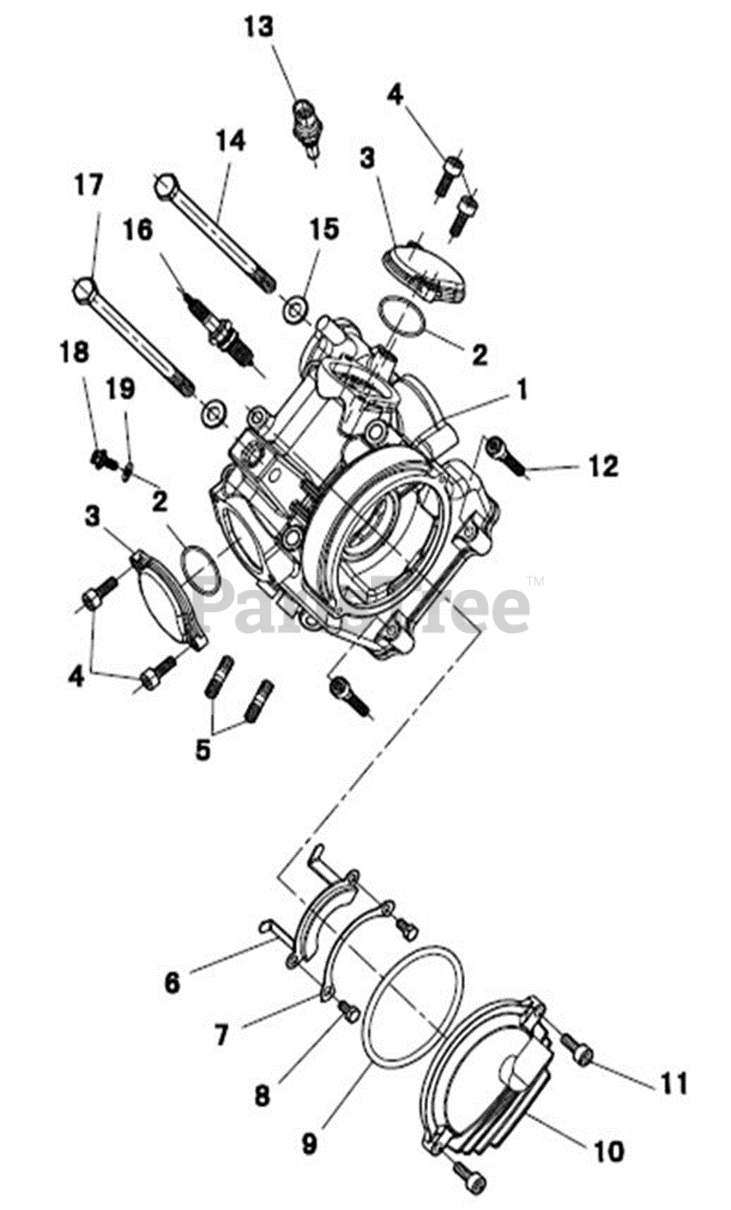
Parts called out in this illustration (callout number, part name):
1	CYLINDER HEAD ASSEMBLY
2	O-RING 58 x 2.4
3	VALVE COVER
4	HEX HEAD CAP SCREWM6X20
5	STUD M8X45
6	CAM BEARING HOLDER
7	BOLTS - SPACING PLATE
8	BOLTS HEXAGON HEAD M6 x 16
9	O-RING 107 x 2.4
10	CAMSHAFT COVER
11	BOLTS HEXAGON FLANGE M6 x 25
12	HEX HEAD CAP SCREW M8X40
13	3 WIRE TEMP SENSOR
14	BOLTS CYLINDER M10X 1.25 x 261
15	COPPER WASHER 10x18x2
16	SPARK PLUG - NGK DR8EA
17	BOLT CYLINDER M10 x 1.25 x 230
18	HEX FLANGE BOLT M6X12
19	ALUMINUM WASHER 6X12X1.5
